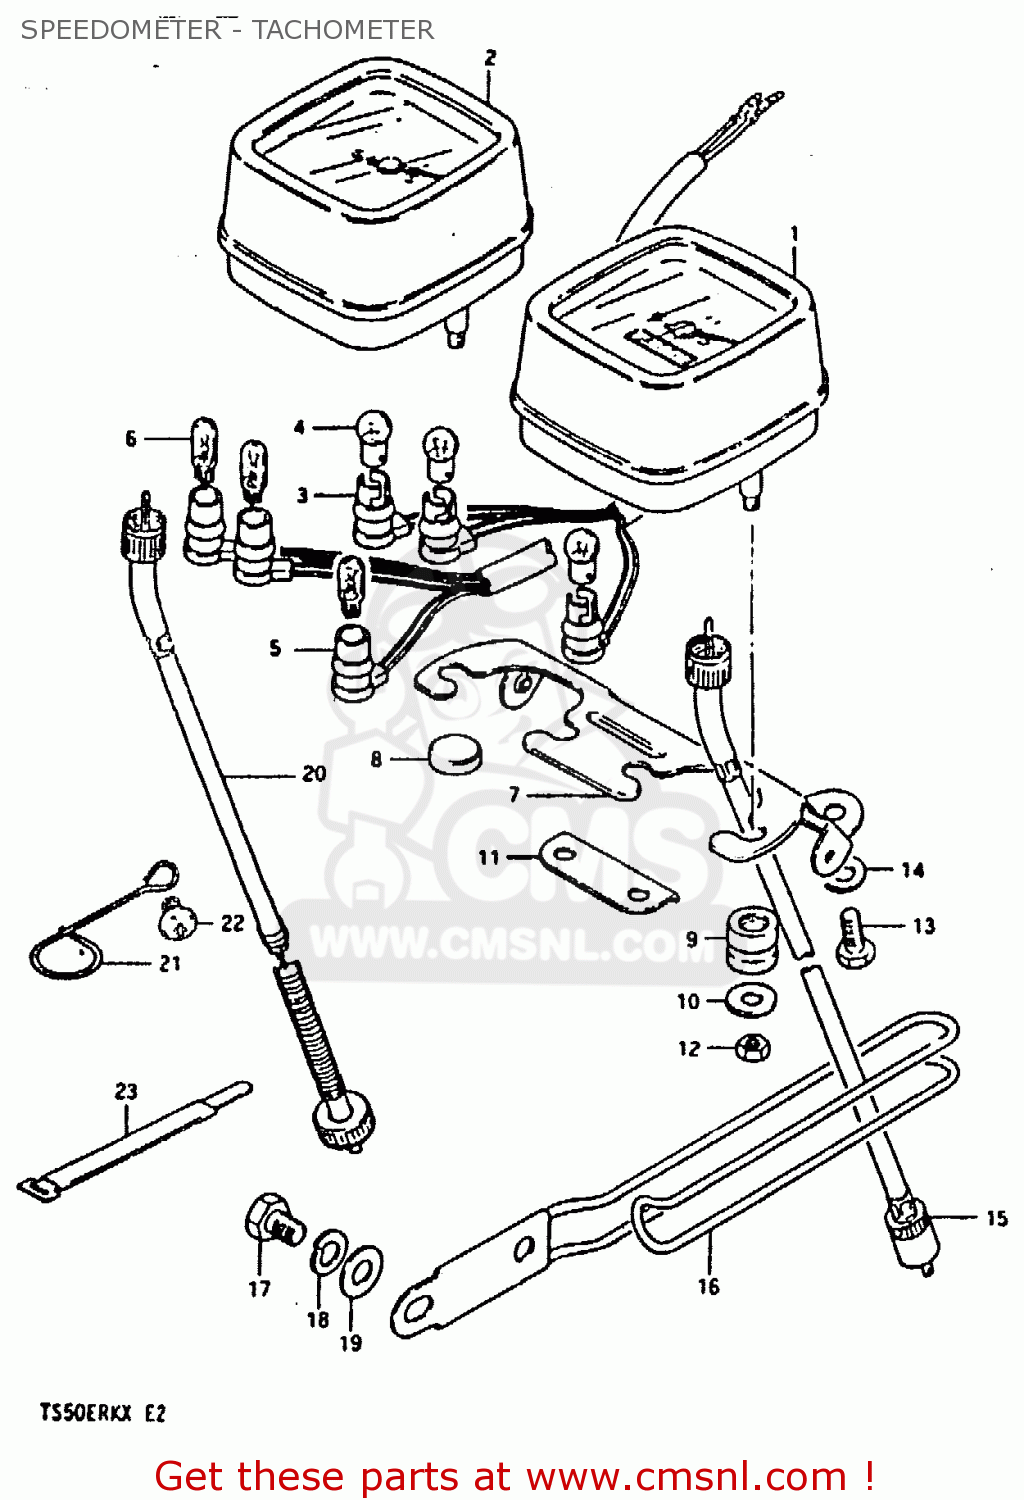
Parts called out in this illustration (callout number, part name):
1	SPEEDOMETER (KILO)
2	METER,TACHOMETER
3	SOCKET
4	BULB(6V1.7W,STANLEY,A61A)
5	SOCKET
6	BULB(6V1.7W,STANLEY,A61A)
7	BRACKET,SPEEDOMETER
8	CUSHION,METER
9	CUSHION
10	WASHER,METER
11	PLATE,METER CONNECTING
12	NUT
13	BOLT, UPPER
14	WASHER
15	CABLE, SPEEDOMETER
16	GUIDE,CABLE
17	BOLT 8X12
18	LOCK WASHER
19	WASHER
20	CABLE, TACHOMETER
21	CLIP
22	BOLT
23	CLAMP
